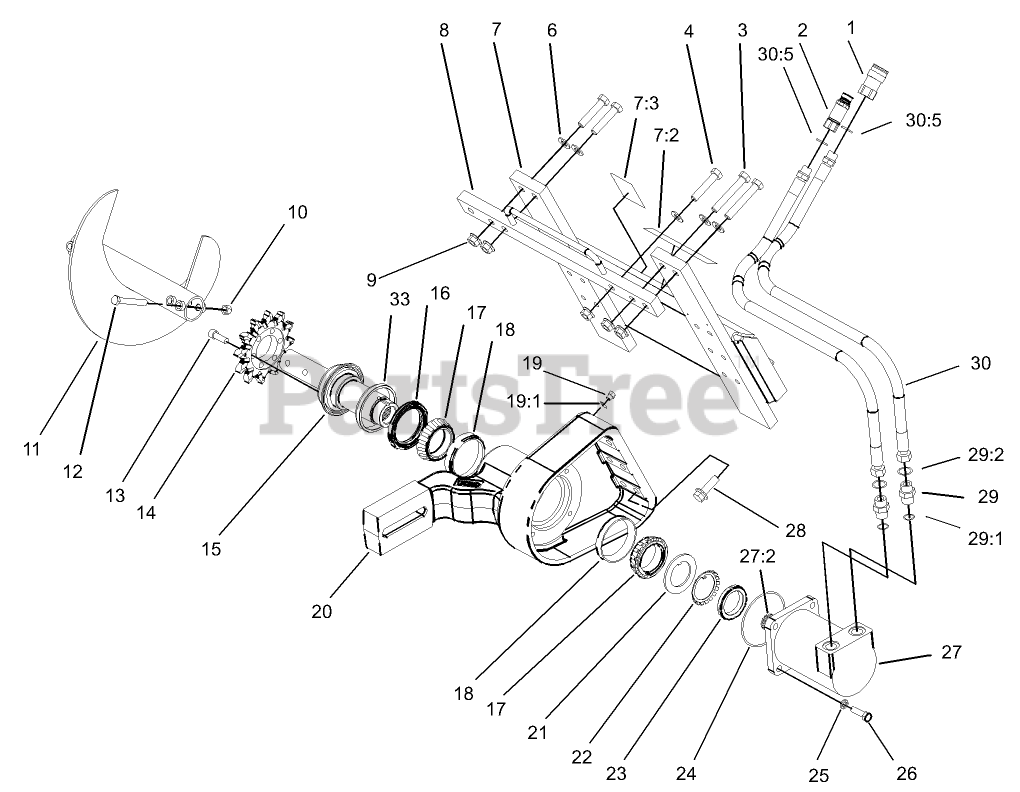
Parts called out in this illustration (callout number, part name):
1	COUPLER-FACE, FLUSH
2	NIPPLE-CONNECT, PRESSURE
3	SCREW-HH
4	SCREW-HH
6	WASHER-FLAT
7	MOUNT ASM
7:2	DECAL-DANGER
7:3	DECAL-DANGER
8	CROSSBAR ASM
9	NUT-FLANGE
10	NUT-LOCK, NI
11	AUGER ASM
12	SCREW-HH
13	SCREW-HSH
14	SPROCKET-TRENCHER
15	SHAFT-TRENCHER
16	SEAL-SHAFT
17	CONE-BEARING
18	CUP-BEARING
19	PLUG ASM
19:1	O-RING
20	MOUNT-BOOM
21	WASHER-TONGUED
22	WASHER-LOCK, BEARING
23	NUT-LOCK, BEARING
24	O-RING
25	WASHER-LOCK
26	SCREW-HH
27	MOTOR-HYD
29	FITTING-STRAIGHT
29:1	O-RING
29:2	O-RING
30	HOSE ASM
30:5	O-RING
33	SPACER
